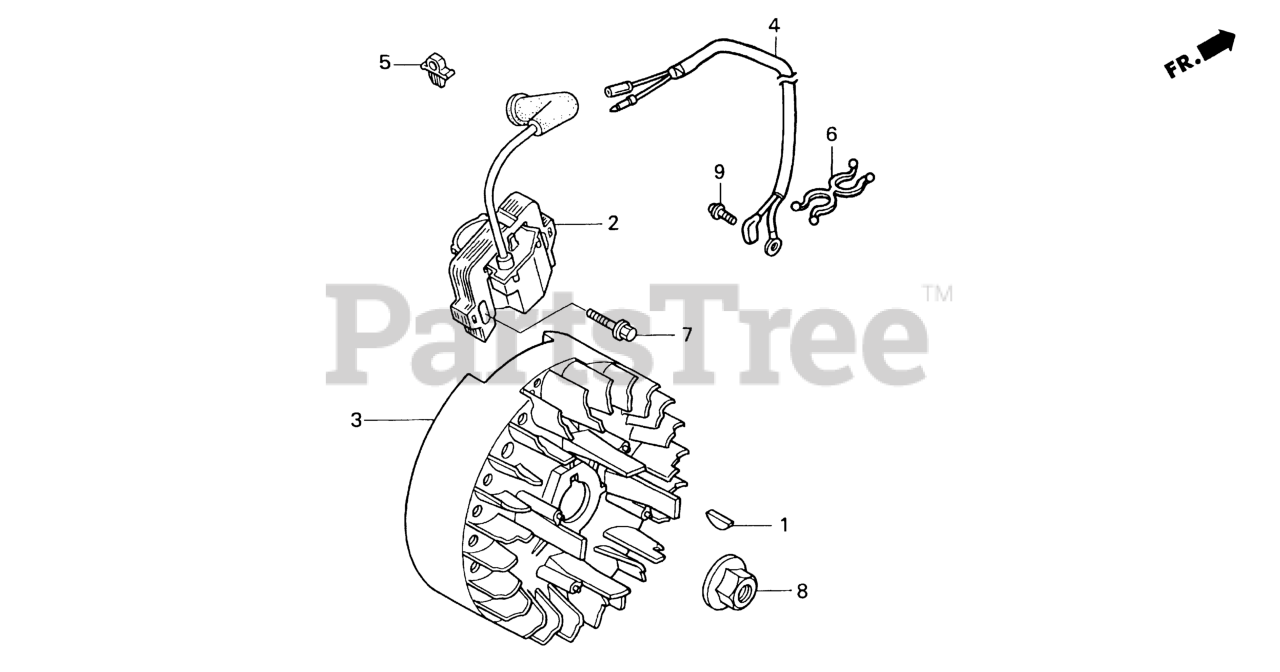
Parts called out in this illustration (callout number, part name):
1	KEY, SPECIAL WOODRUFF (25X18)
2	COIL ASSY., IGNITION (USE FOR F/W OF TEC) (TEC) Use up to Engine SN 3747197.
3	FLYWHEEL COMP. (TEC) (USE FOR IGN. COIL OF TEC) (USE FOR TEC IGNITION COIL)
4	WIRE, STOP SWITCH
5	CLIP, BRAKE PIPE (A) (FOR NEUTRAL SWITCH)
6	CLIP D, SPEEDOMETER CABLE
7	BOLT, FLANGE (6X20) (CT200)
8	NUT, SPECIAL (14MM)
9	SCREW-WASHER (5X8)
